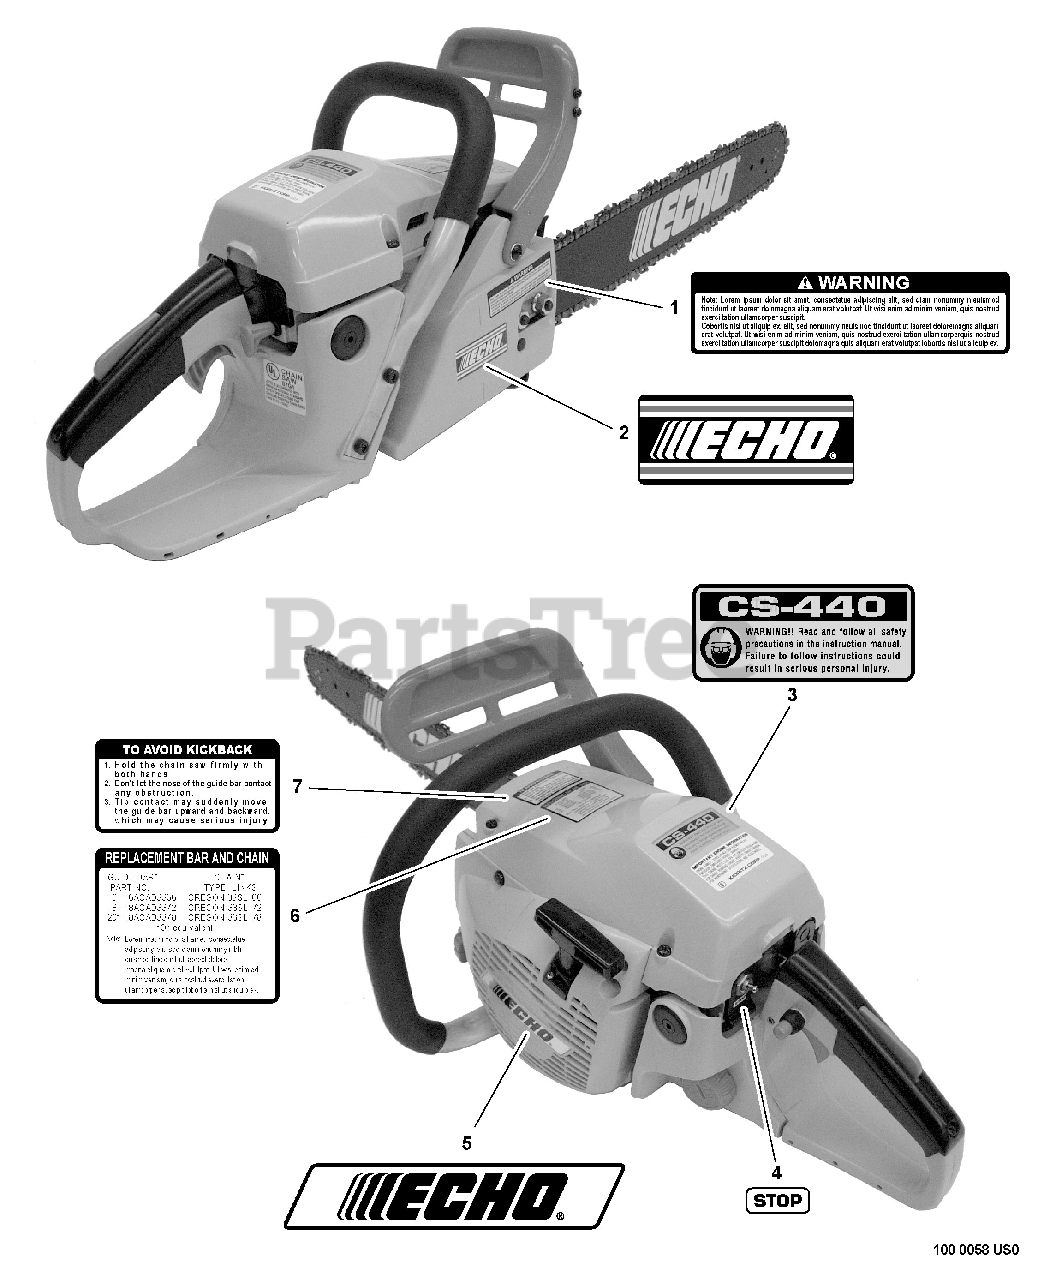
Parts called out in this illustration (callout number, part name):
1	LABEL - WARNING
2	LABEL - ECHO
3	LABEL - MODEL CS-440
4	LABEL - STOP
5	LABEL - ECHO
6	LABEL - BAR & CHAIN
7	LABEL - KICK BACK
